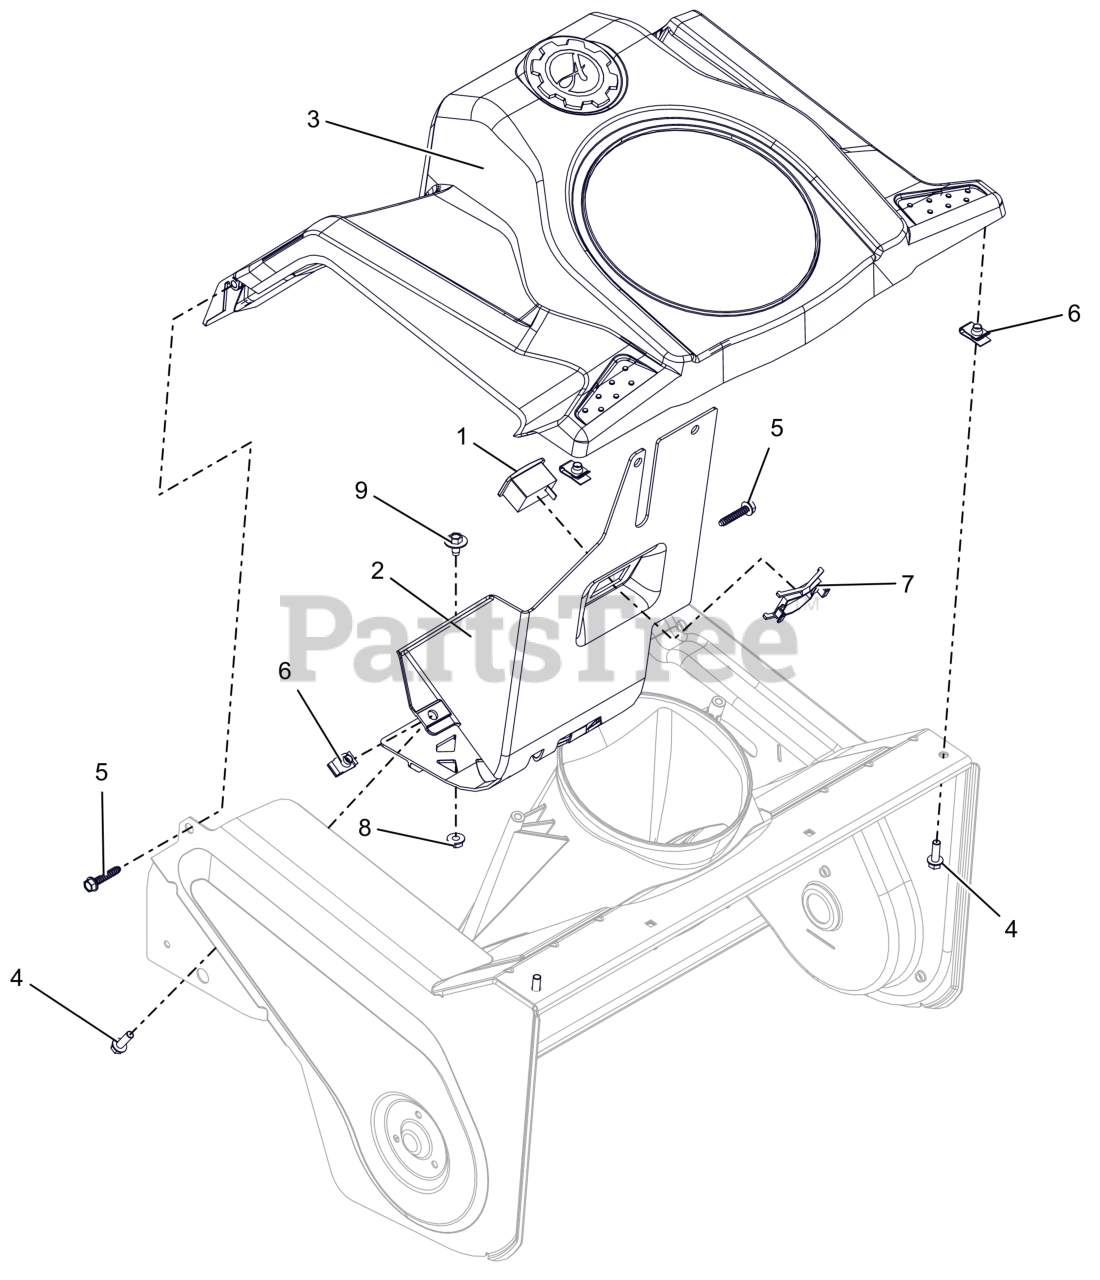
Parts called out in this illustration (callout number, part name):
1	METER, HOUR INDCTV RECOIL ENG
2	COVER, BACK
3	COVER, HOUSING - W/DECAL
4	BLT, HWH .25-20X.75 G5 ZCC
5	SCR,PLASTITE .25-10X1.25 ZCC
6	NUT-RTNR .25-20X.56
7	HOUR, METER - QUICK CLIP
8	NUT-LK-TOP-FLG .250-20 GF ZCC
9	SCR, TAP .25-20X.50 LG HWH ZCC
